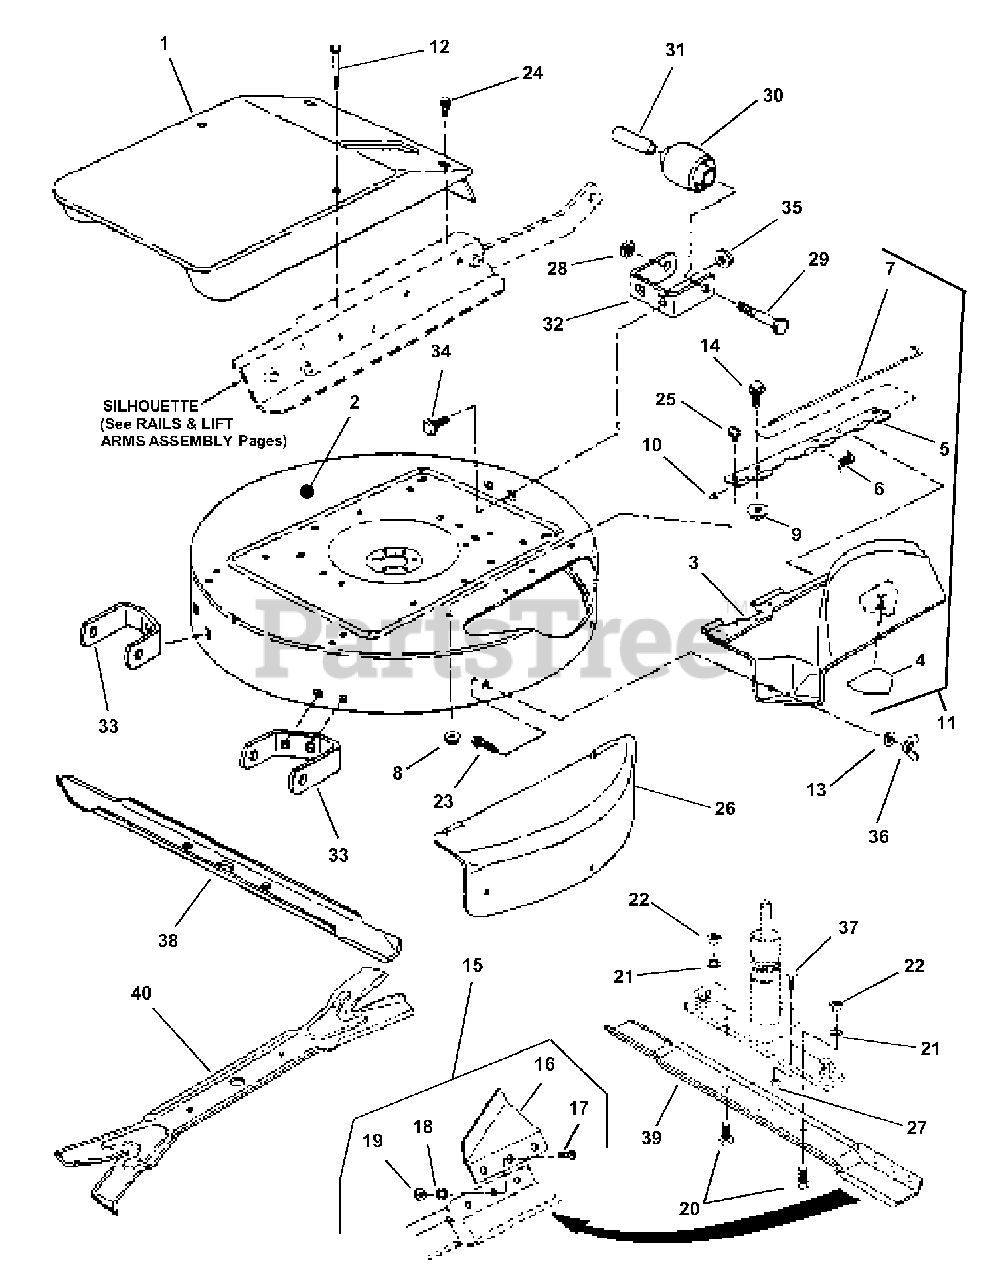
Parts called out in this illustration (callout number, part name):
1	COVER, Spindle
2	DECK, 25" Replacement (Painted deck with decals)
2	DECK, 28" Replacement (Painted deck with decals)
2	DECK, 33" Replacement (Painted deck with decals)
3	DEFLECTOR, Discharge (25" Deck)
3	DEFLECTOR, Discharge (28" & 33" Deck)
4	DECAL, DANGER (Cut Finger)
5	HINGE, Deflector
6	SPRING, Hinge
7	PIN, Hinge
8	NUT, 5/16-18 Hex Flange Lock
9	NUT, 1/4-20 Hex Flange Lock
10	NUT, Push
11	ASSEMBLY, Discharge (25" Deck)
11	DEFLECTOR, Discharge (28" & 33" Deck)
12	SCREW, 1/4-20 x 3-1/2" Hex Washer Self-Tap, Gr. 5
13	WASHER, 5/16 Flat
14	BOLT, 1/4-20 x 1/2" Hex Flange Lock
15	AIR LIFT KIT, Hi-Vac
16	AIR LIFT, Hi-Vac (3 hole)
17	SCREW, 5/16-24 x 11/16" Machine
18	WASHER, 5/16-24 Internal Tooth Lock
19	NUT, 5/16-24 Hex
20	SCREW, 1/2-20 x 1" Hex Head Cap, Grade 5
21	WASHER, 1/2 Internal Tooth Lock
22	NUT, 1/2-20 Hex Jam
23	BOLT, 5/16-18 x 3/4" Short Neck Carriage, Grade 5
24	SCREW, 1/4-20 x 5/8" Hex Self-Tap w/ Captured Washer
25	BOLT, 5/16-18 x 1/2" Hex Flange Lock
26	COVER, 25" Mulcher
26	COVER, 28" Mulcher
26	COVER, 33" Mulcher
27	NUT, 3/18-16 Hex Flange Lock
28	NUT, 3/8-24 Hex Nyloc
29	SCREW, 38-24 x 3-3/4" Hex Head Cap, Grade 5
30	WHEEL, Gage
31	SPACER
32	BRACKET, Gage Wheel (Front)
33	BRACKET, Gage Wheel (Rear)
34	BOLT, 5/16-18 x 1/2" Short Neck Carriage, Grade 5
35	NUT, 5/16-18 Hex Flange Lock
36	NUT, 5/16-18 Wing
37	BOLT, 3/8-16 x 3/4" Hex Flange Lock
38	BLADE, 25" Mulcher
38	BLADE, 28" Mulcher
38	BLADE, 33" Mulcher
39	25" BLADE
39	28" BLADE
39	33" BLADE
40	BLADE, Ninja, 25"
40	BLADE, Ninja, 28"
40	BLADE, Ninja, 33"
